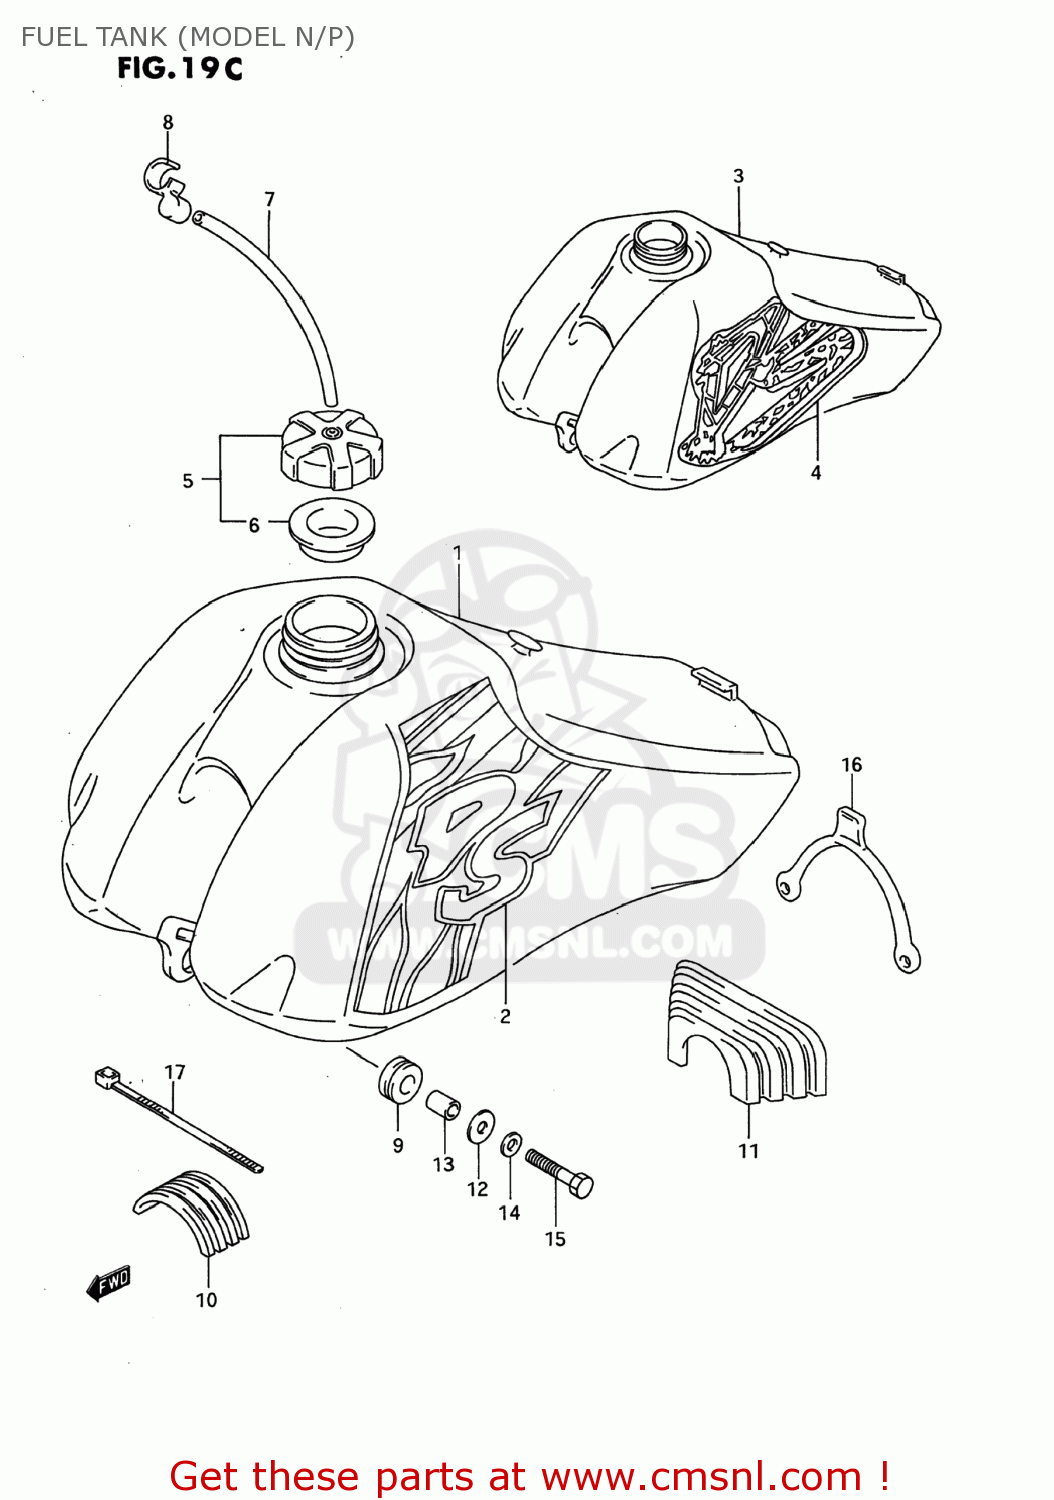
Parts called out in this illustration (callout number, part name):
1	TANK ASSEMBLY,FUEL
2	TAPE SET,FUEL TANK
3	TANK ASSEMBLY,FUEL
4	EMBLEM SET,FUEL TANK
5	CAP SET,FUEL TANK
6	GASKET,FUEL TANK CAP (NAS)
7	HOSE(5X8.2X600)
8	CLAMP
9	CUSHION
10	CUSHION,FUEL TANK UPR FR
11	CUSHION,FUEL TANK UPR RR
12	WASHER (6.5X24X1.6)
13	SPACER (6.5X10.5X13.5)
14	WASHER,LOCK
15	BOLT
16	BAND,FUEL TANK RR
17	CLAMP
